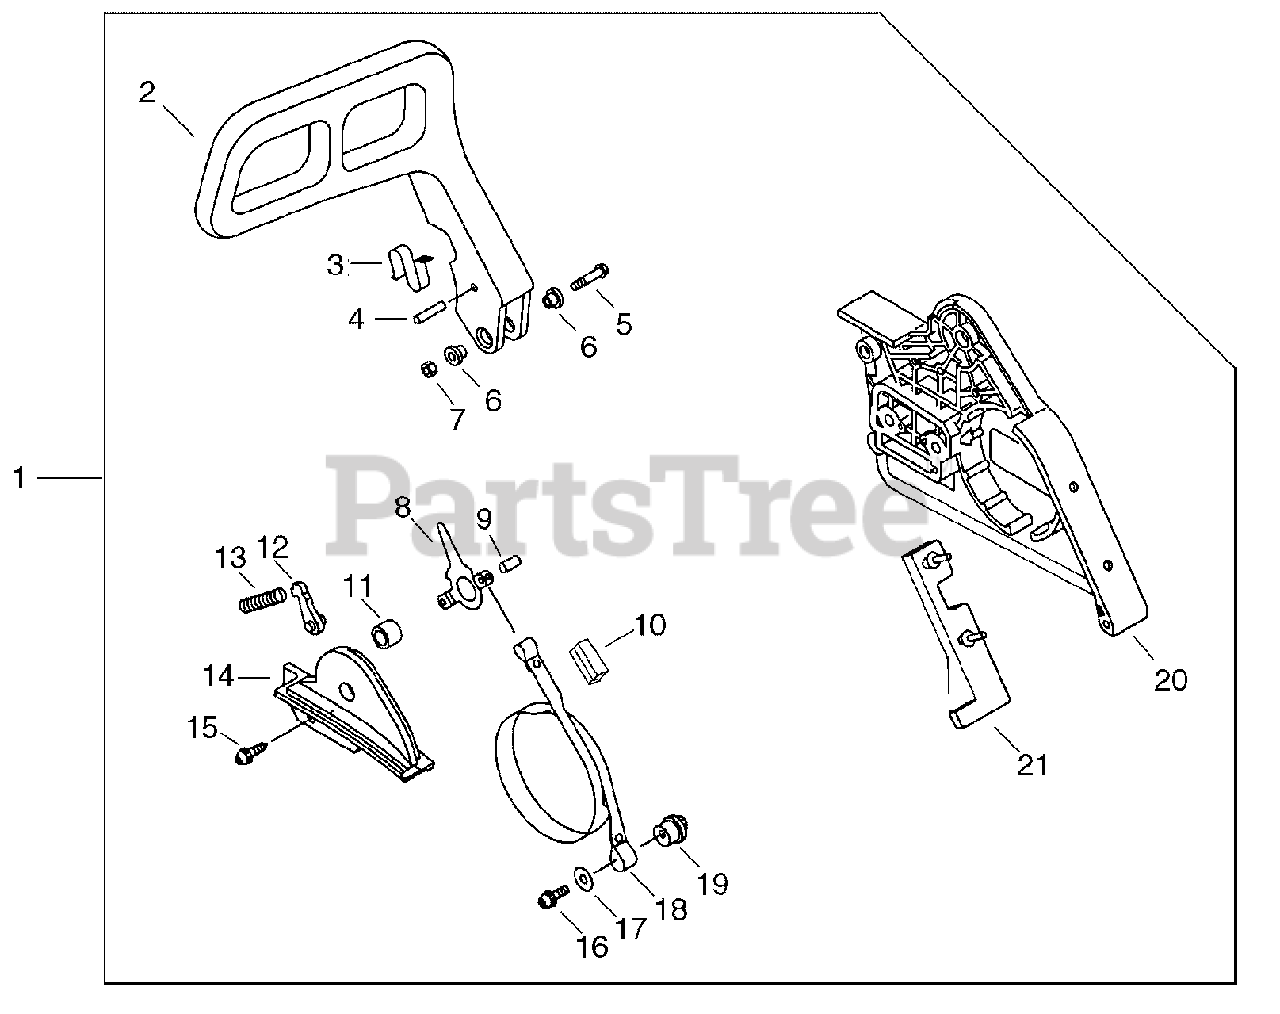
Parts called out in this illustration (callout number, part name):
1	CHAIN BRAKE ASSY
2	LEVER, BRAKE
4	PIN - 3.5X26
5	SCREW - 5X32
7	LOCKNUT - 5
8	LEVER, BRAKE
9	PIN - SPRING -- 4X8
11	WASHER - 5
12	STOPPER, BRAKE
13	SPRING, BRAKE
14	COVER, BRAKE
15	SCREW - 4X10
16	SCREW - 5X25
18	BAND, BRAKE
19	ADJUSTER, BRAKE BAND
20	GUARD, SPROCKET
21	PAD, GUARD
